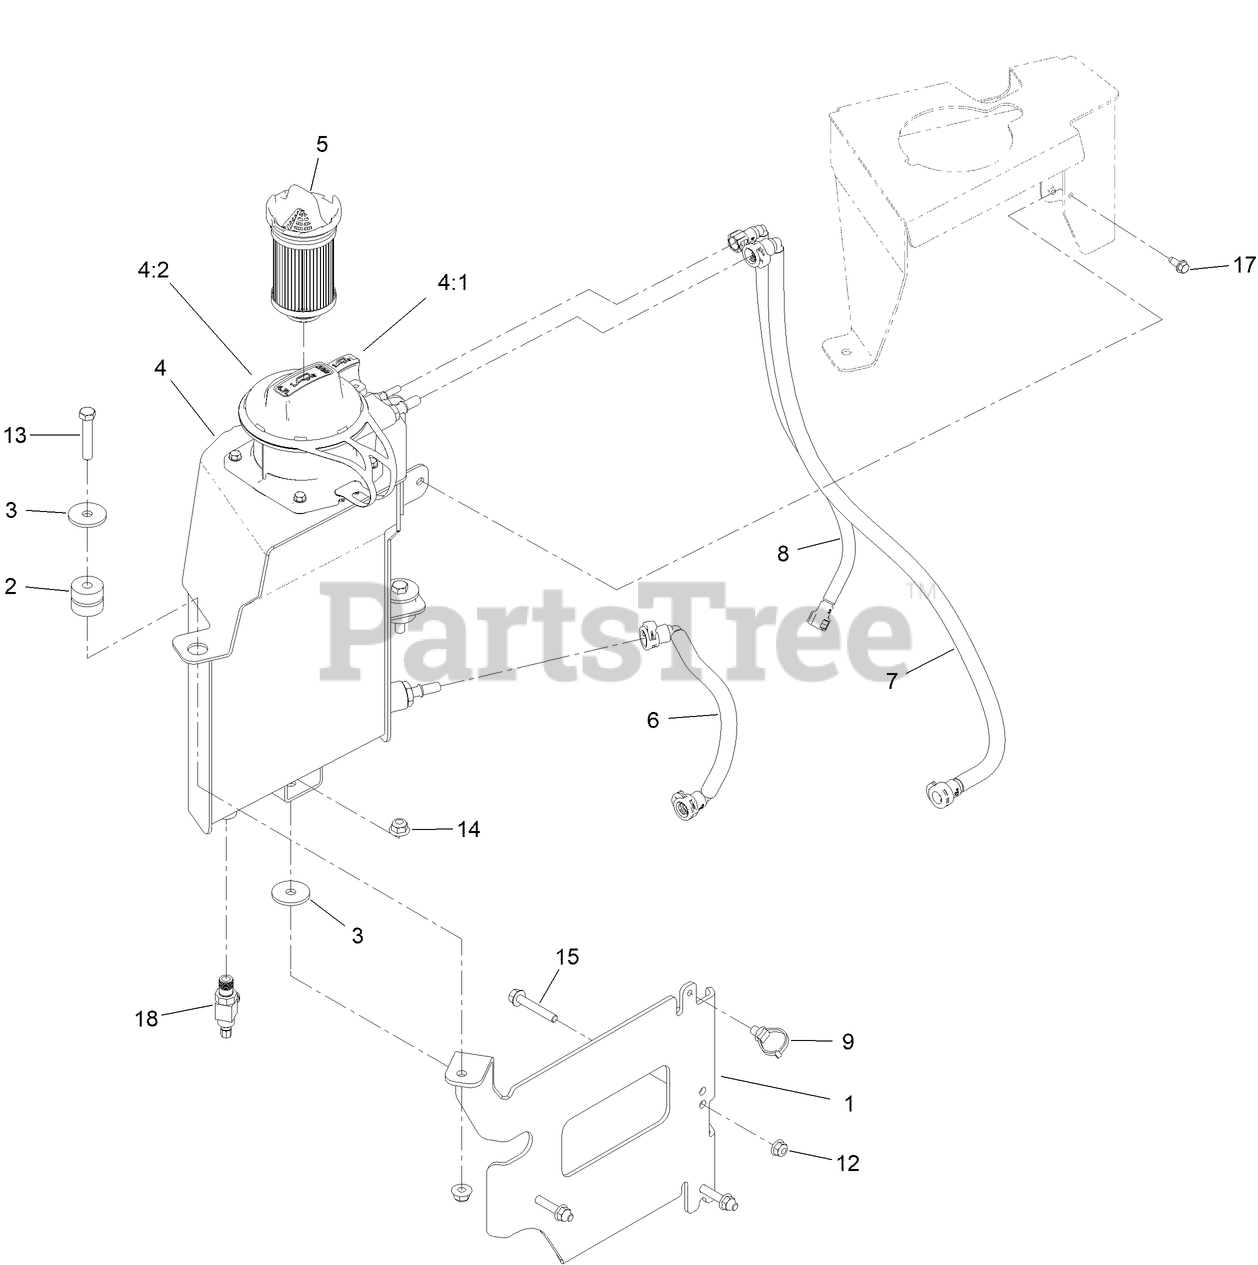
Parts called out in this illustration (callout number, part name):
1	MOUNT-TANK, OIL
2	ISOLATOR-TANK
3	WASHER
4	RESERVOIR-OIL
4:1	OIL DIPSTICK ASM
4:2	OIL TANK CAP ASM
5	FILTER-OIL
6	HOSE-SUPPLY
7	HOSE-SCAVENGE
8	HOSE-VENT
9	CLIP-TIE
12	NUT-HF, NI
13	SCREW-HH
14	NUT-HF, NI
15	SCREW-HHF
17	SCREW-HWH
18	VALVE-OIL DRAIN
